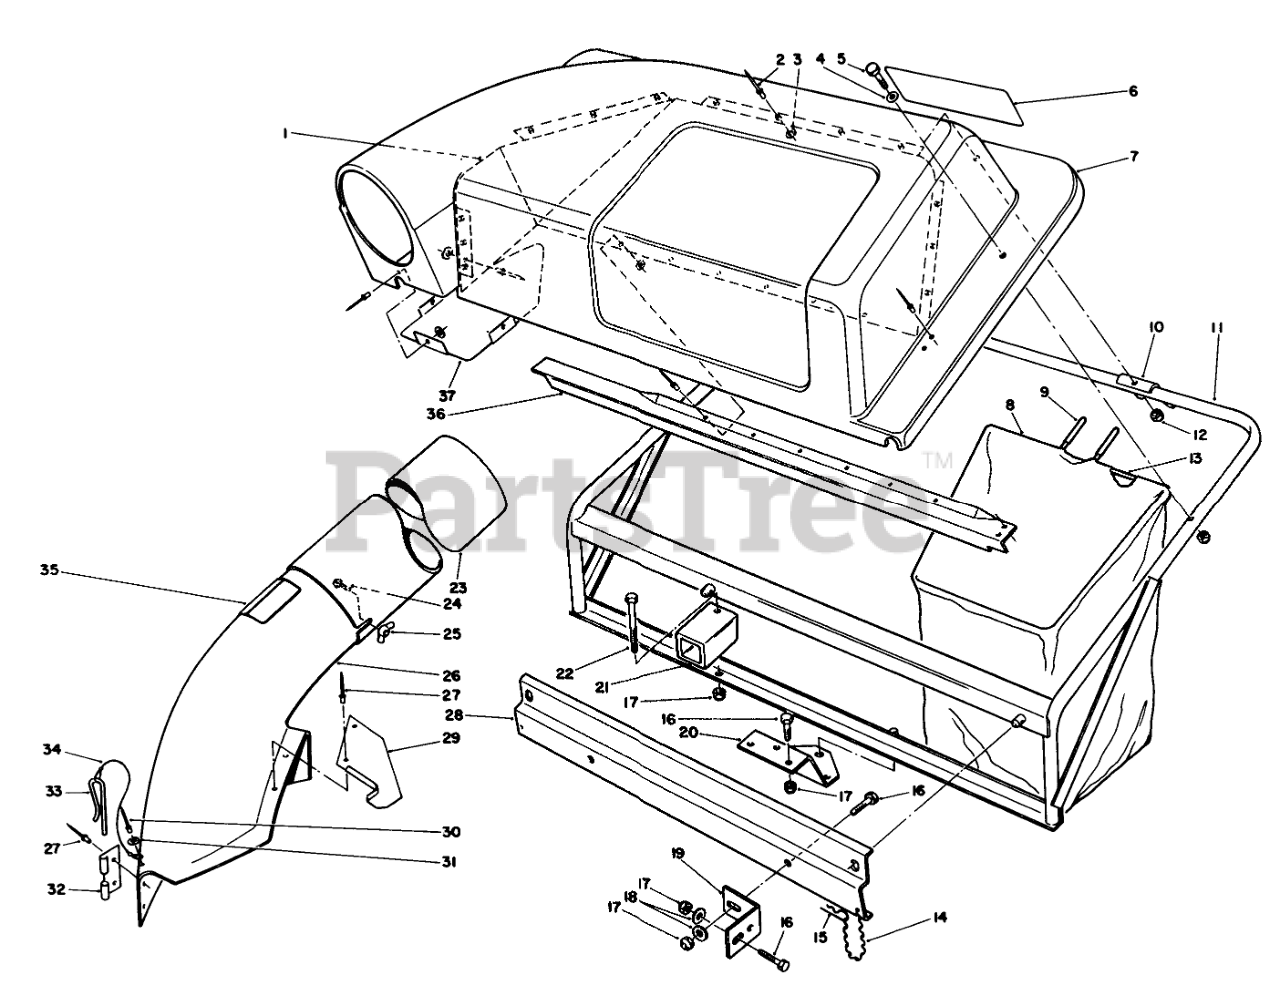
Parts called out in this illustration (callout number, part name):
1	Screen-Cover
2	Rivet-Pop
3	WASHER-FLAT
4	WASHER-PLAIN
5	SCREW-HH
6	TWIN BAGGER DECAL
7	Cover
8	Bag-Twin Bagger (Incl. Ref. #9 & 13)
9	GRIP-HANDLE, BAG
10	BAG FRAME BRKT
11	Frame
12	NUT-LOCK, CAP
13	Frame-Bag
14	6-LINK CHAIN W/HOOK
15	PIN-HAIR
16	Screw
17	NUT-LOCK, NI
18	WASHER-PLAIN
19	MTG BRACKET
20	MTG PLATE B
21	FRAME SUPT TUBE B
22	SCREW-HH
23	TUBE(ROUND&LONG)
24	BOLT-CARR
25	NUT-WING SPECL
26	Chute Assembly (Incl. Ref. #27, 29-35)
27	RIVET-BLIND
28	Bracket Frame Support
29	CHUTE SUPT BRKT
30	RIVET-BLIND
31	WASHER-PLAIN
32	BRACKET-MOUNTING, CHUTE
33	PIN-LOCKING, CHUTE
34	LANYARD
35	DECAL-DANGER
36	SCREEN SUPT BRKT B
37	Shield Cover
